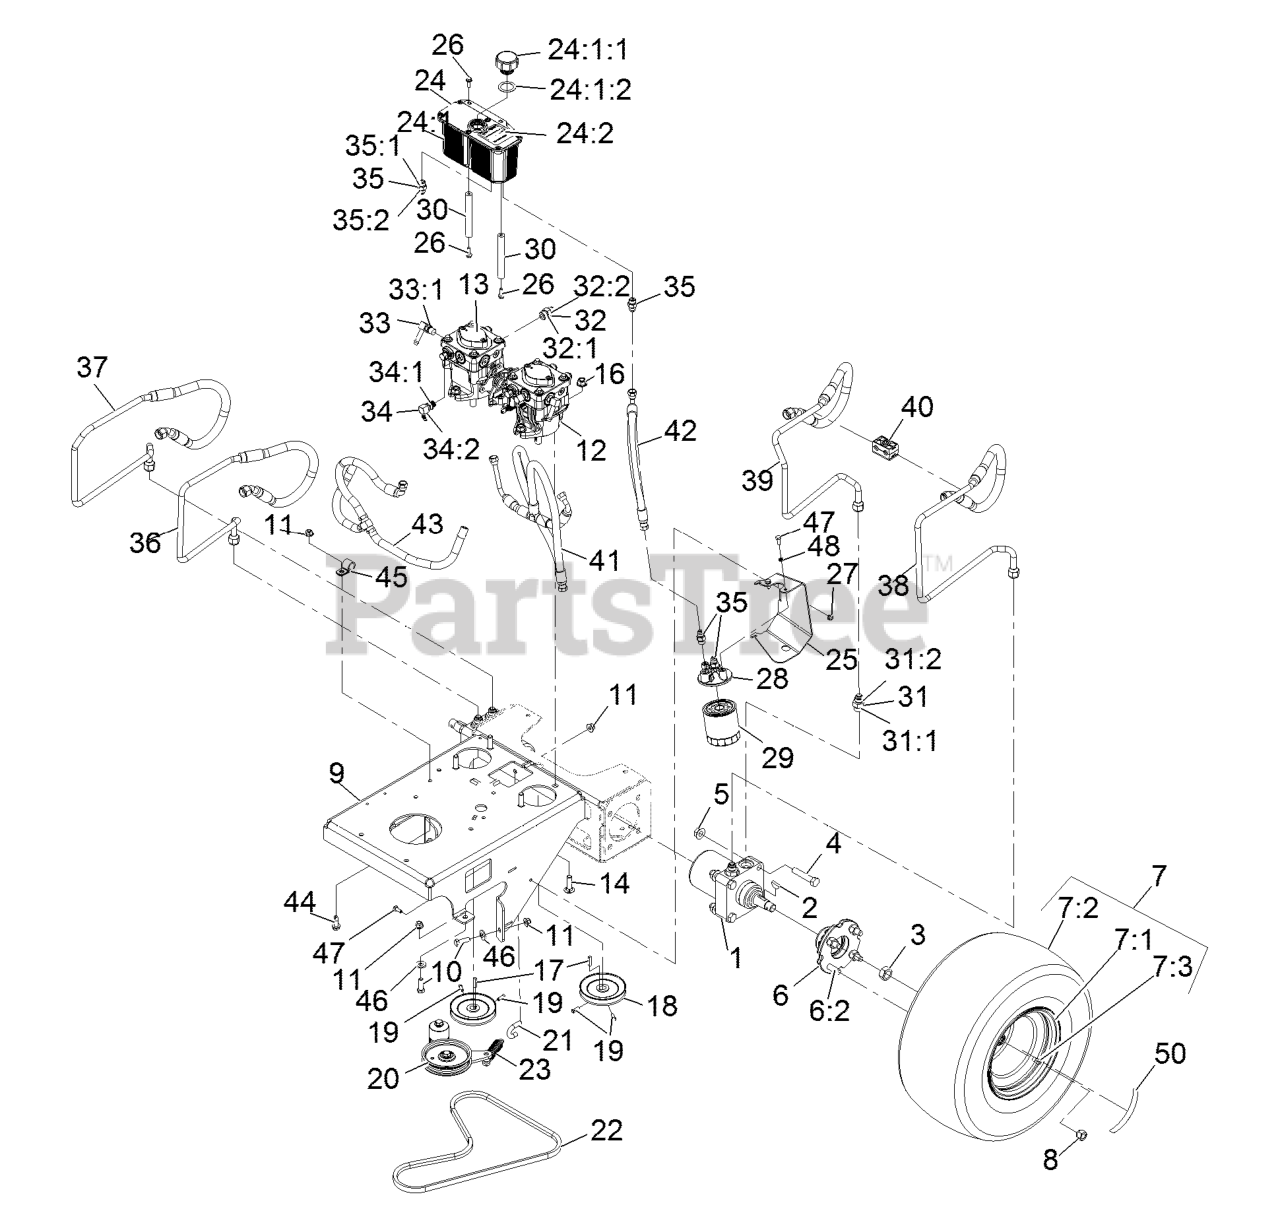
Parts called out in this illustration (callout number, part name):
1	HYD MOTOR ASM
2	KEY-WOODRUFF
3	NUT-MOTOR, WHEEL
4	SCREW-HH
6	WHEEL HUB ASM
6:2	STUD-TYPE, DRIVE
7	WHEEL/TIRE ASM
7:1	RIM-8 INCH
7:3	Stem-Valve
8	NUT-LUG
9	BASE, ENGINE
10	SCREW-HH
11	NUT-HF, NI
12	PUMP - HYDRAULIC
13	PUMP-HYDRAULIC
14	SCREW-HH
16	NUT-HF, NI
18	PULLEY-PUMP
19	SCREW-SET
20	Pump Idler Asm
21	ANCHOR, SPRING
22	BELT-V
23	SPRING-EXTENSION
24	RESERVOIR ASM
24:1	Reservoir-Hyd
24:1:1	Cap-Reservoir, HYD
24:1:2	GASKET-CAP
24:2	DECAL-HYDRAULIC TANK
25	PLATE-FILTER MOUNT
26	SCREW-HHF
28	HEAD-FILTER
29	FILTER-25 MICRON, BI-DIRE
30	ROD-RESERVOIR STAND
31	FITTING-STRAIGHT
31:1	O-RING
32	FITTING-STRAIGHT
33	FITTING-ELBOW, 90
33:1	O-RING
34	FITTING-90 DEG
35	FITTING-STRAIGHT
36	HOSE-HARDLINE
37	HOSE-HARDLINE
38	HOSE-HARDLINE
39	HOSE-HARDLINE
40	CLAMP, STAUFF 212,7/12,7
41	HOSE-ASM CHARGE
42	HOSE ASM-HYD LP 3/8X14.4
43	HOSE ASM - HYD 3/8
44	SCREW-TAPPING
45	CLIP-LOOM
46	WASHER-BELLEVILLE
47	SCREW-HH
48	WASHER-LOCK
